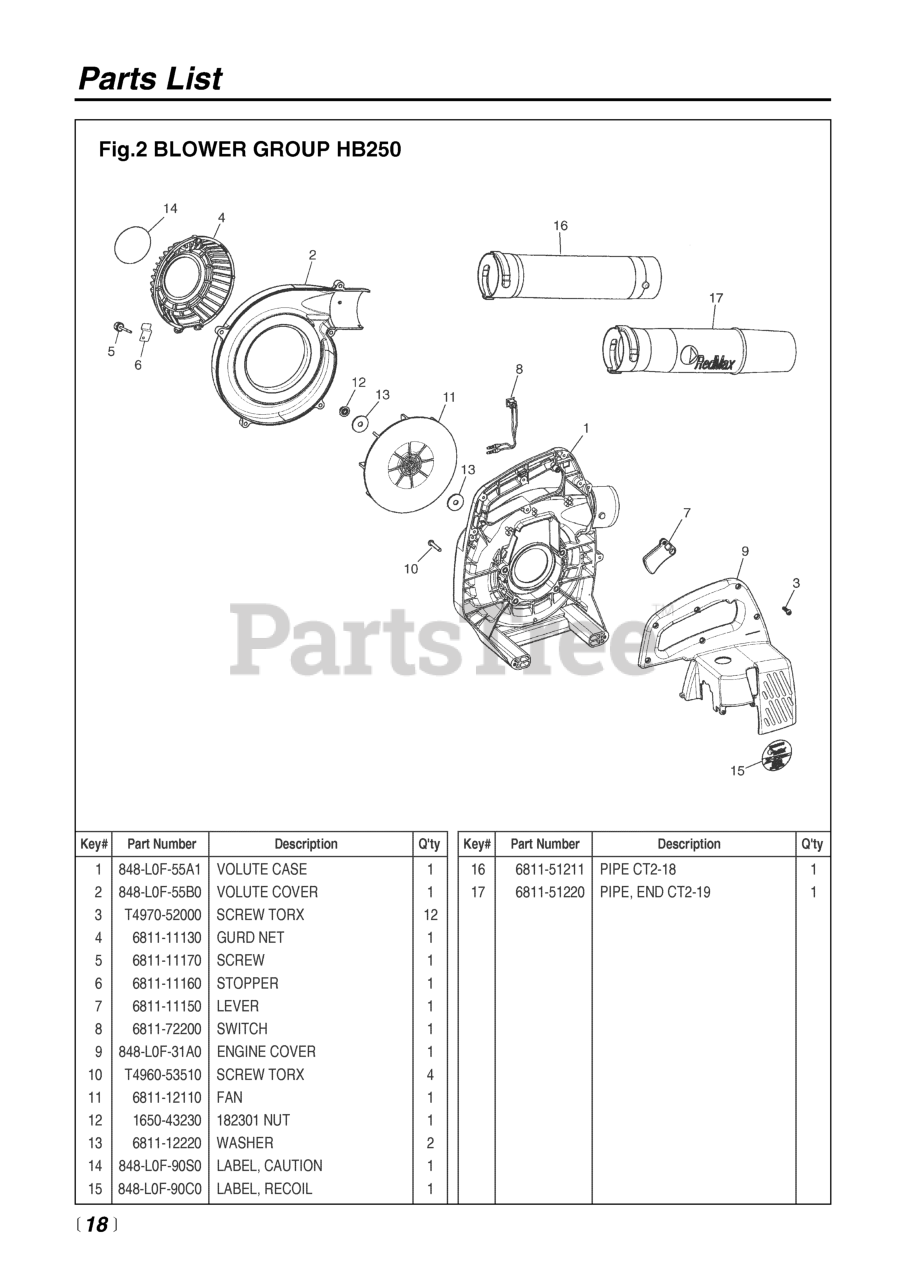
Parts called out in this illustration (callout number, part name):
1	VOLUTE CASE (RPLS. 6811-11110)
2	VOLUTE COVER
3	SCREW TORX
4	GUARD
5	SCREW
7	LEVER
8	SWITCH
9	ENGINE COVER
10	SCREW TORX
11	FAN
12	NUT
13	WASHER
14	LABEL, CAUTION
15	LABEL, RECOIL
16	PIPE, STRAIGHT
17	PIPE, END
